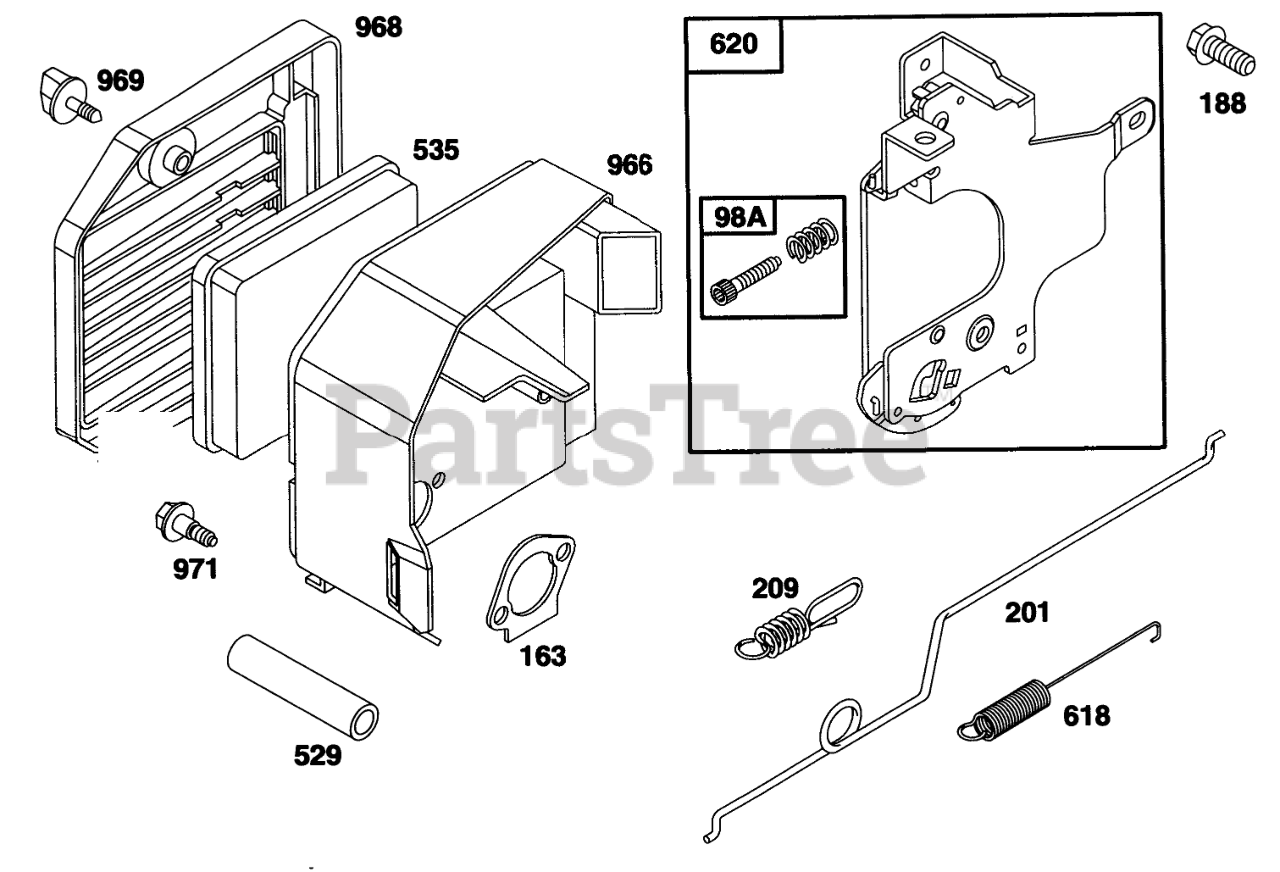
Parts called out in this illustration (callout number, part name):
37	GUARD - FLYWHEEL
98A	SPEED ADJUST. SCREW ASM
163	AIR CLEANER GASKET
188	Screw-Cap
201	GOVERNOR LINK
209	GOVERNOR SPRING
529	TUBE - BREATHER
535	FILTER ELEMENT
618	RETURN SPRING
620	CARBURETOR BRACKET
966	AIR CLEANER BASE
968	AIR CLEANER COVER
969	AIR CLEANER SCREW
971	AIR CLEANER SCREW
